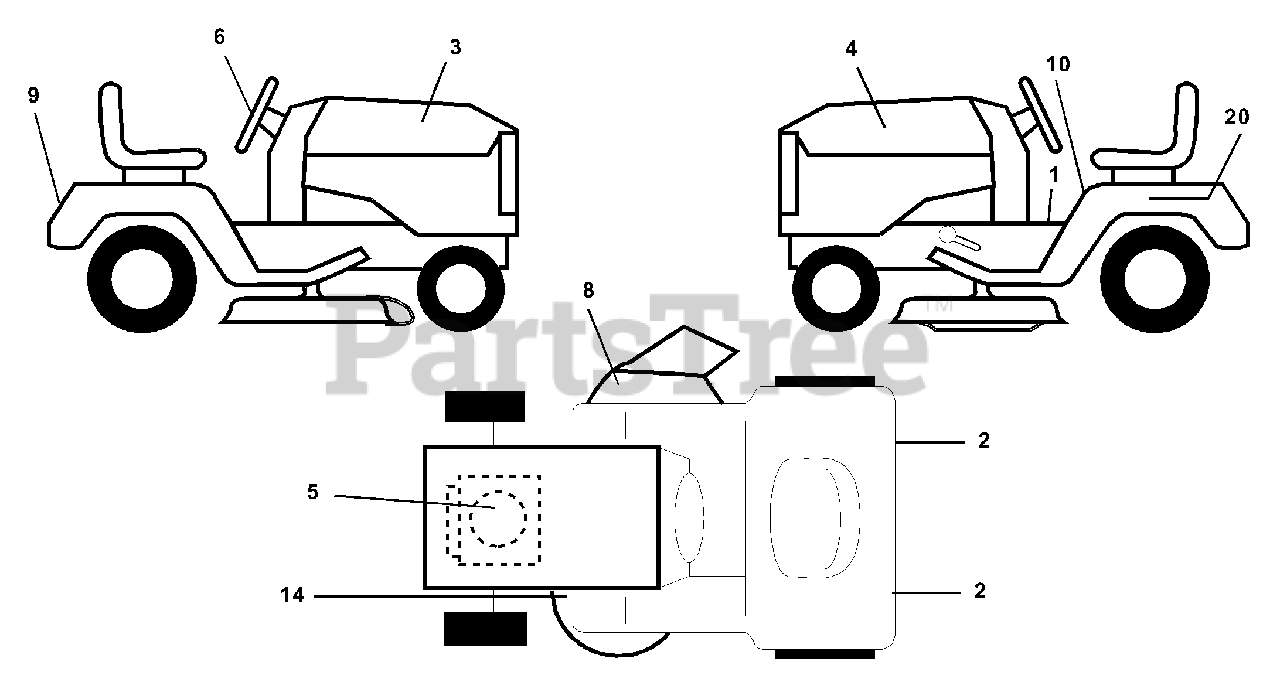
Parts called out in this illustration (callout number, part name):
1	Decal Oper. Step Thru Eng/Fr
2	Reflector Tail Light Red/Amber
3	Decal Hood RH
4	Decal Hood LH
5	Decal HP Engine
6	Decal Steer Wheel
8	Decal Warning
9	Decal Fender Husq
10	Decal Fender Danger Eng/Fr
14	Decal V-Belt Schematic
20	Decal Bat Dan/Psn
